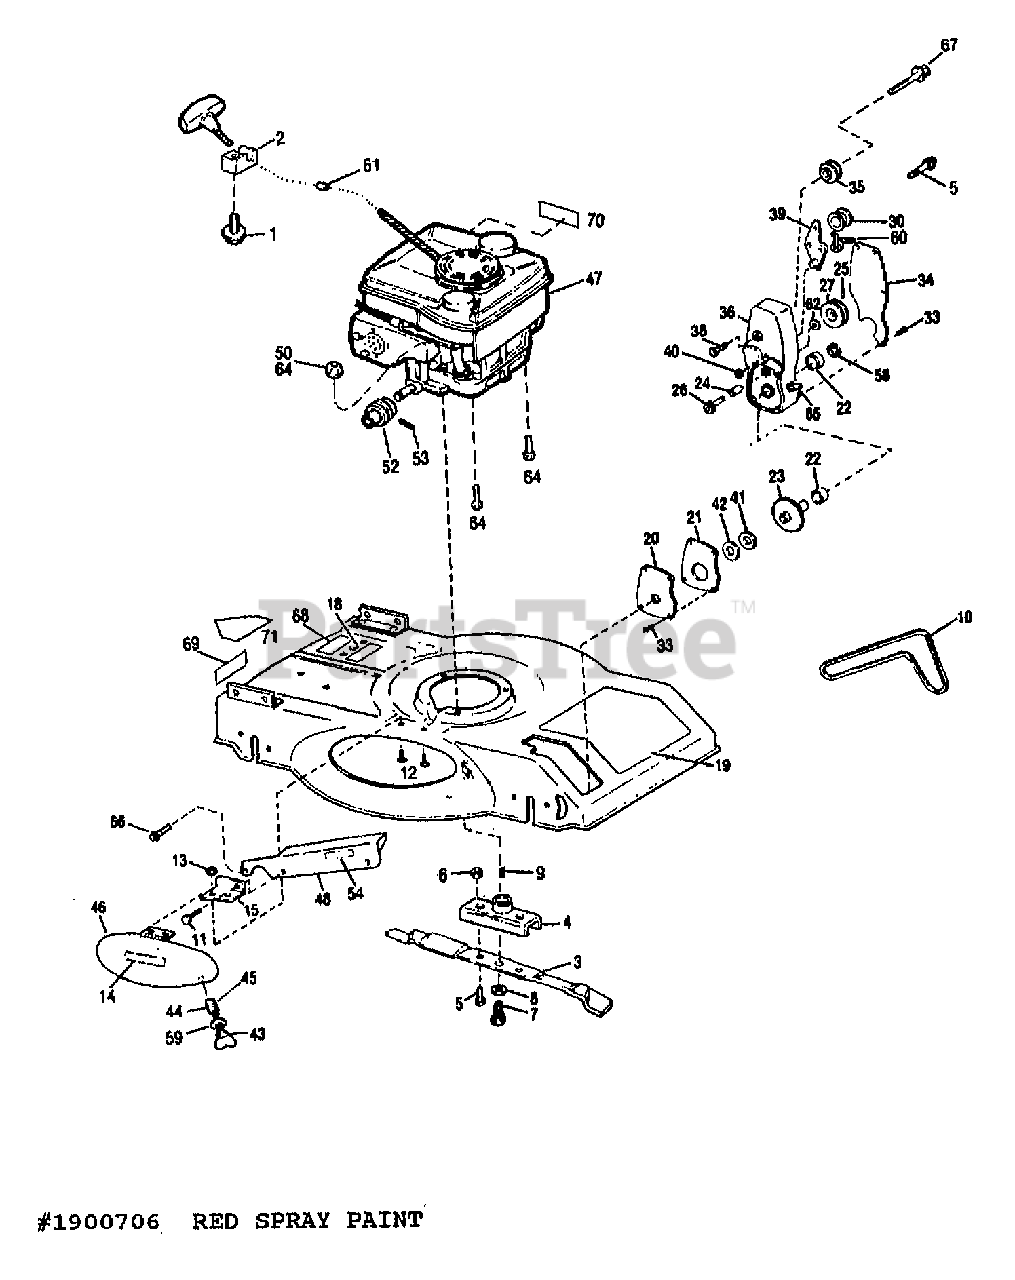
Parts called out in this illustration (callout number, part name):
1	SCR-HFLK 1/4-20X1.0 THFRM {NOT 8656R/RS}
2	GUIDE-ROPE {NOT 8656R/RS}
3	BLADE-22" MULCHER
4	ASSM-BLADE COUPLING
5	SCR-HH 3/8-16X1.0 G5 ZP
6	NUT-LOCK 3/8-16
7	SCR-SHOULDER
8	WASHER-LK .5
9	KEY-WOODRUFF
10	BELT-DRIVE
11	SCR-SHOULDER
12	SCR-CARR 1/4-20X.375
13	NUT-HF/LK 1/4-20 ZP
14	DECAL-CAUTION
15	BRKT-SUPPORT
18	DECAL-CUTTING HEIGHT
19	DECAL-LOGO
20	COVER-GEAR CASE BOTTOM
21	GASKET-GEAR CASE
22	BEARING-BRONZE
23	ASSM-GEAR SHAFT
24	BEARING-BRONZE
25	PIN-DRIVE .218X1.12
26	ASSM-STEEL PINION SHAFT
27	SHEAVE
30	IDLER-FLAT
33	SCR-HW M10-24X.5 STH ZP
34	COVER-GEAR CASE TOP
35	SHEAVE
36	ASSM-GEAR CASE
38	SCR-SHOULDER
39	ASSM-IDLER ARM
40	NUT-PUSH 3/8 ZP
41	WASHER-1.5X.755X.062
42	WASHER-FELT
43	PIN-CHUTE LOCK
44	SPRING-COMPRESSION
45	PIN-ROLL .093 DIAX.62
46	COVER-DISCHARGE W/DECAL (INCL. 14)
47	B & S ENG, 4.0 HP, #122782 RCL STR (8654R/RS)
47	B & S ENG, 5.0 HP, #124782 RCL STR (8655R/RS)
47	B & S ENG, 5.0 HP #124787 ELEC STR (8656R/RS)
48	ASSM-BELT COVER
49	SCR-HH 5/16-18X1.25 G5ZP
52	SHEAVE
53	PIN-ROLL
54	DECAL-FRONT WHEEL DRIVE
58	RING-GRIP EXT .5 ID
59	WASHER-.75X.312X.065 ZP
60	SPRING-TORSION
61	STOP-STARTER ROPE {NOT 8656R/RS}
62	WASHER-SHIM
64	SCR-HH 3/8-16X1.0 THDFM
65	FITTING-GREASE 1/4-28X2.00
66	SCR-FLANGE 1/4-20X3/4 GR5
67	SCR-HH 5/16-18X.875 G5 ZP
68	DECAL-U.S.A.
69	DECAL-SOUND LEVEL
70	DECAL-ENGINE (SEARS) {RS}
71	GUARD-ASC {NOT 8656R/RS}
